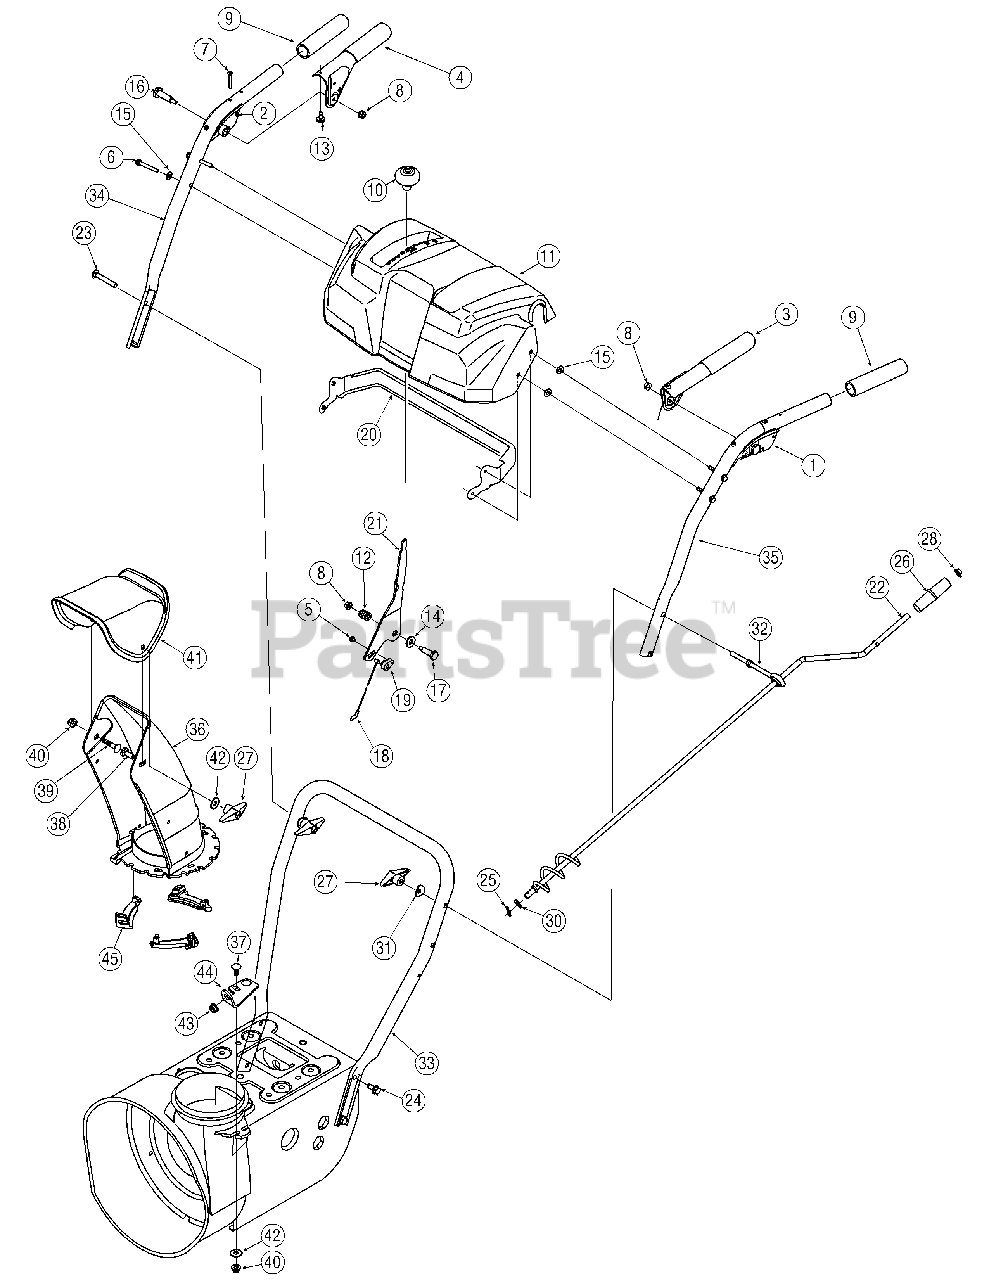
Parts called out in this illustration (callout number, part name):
1	Handle Assembly, Lock, LH
2	Handle Assembly, Lock, RH
3	Handle Ass’ y, Engagement LH
4	Handle Ass’y, Engagement, RH
5	Screw, #10-16, 0.500
6	Screw, 1/4-20, 1.750
7	Screw, Machine, #10-24, 1.375
8	Nut, Flange Lock, 1/4-20, Nylon
9	Grip, 1.0 ID x 5.0
10	Knob, Shift
11	Handle Panel, N-Style
12	Spring, .39 x .60 x .88
13	Bumper, Rubber, .62 OD x .22
14	Washer, Flat, .385 x .870 x .092
15	Washer, Flat, .25 x .630 x.0515
16	Screw, Shoulder, .43 x 1.34, 1/4-20
17	Screw, Shoulder, .374 Dia. X1.05
18	Cable, Speed Selector
19	Barrel Houlder, Cable, LH
23	Screw, Carriage, 5/16-18, 2.25
24	Screw, 5/16-18, 0.75, Gr5
25	Pin, Cotter, .072 x 1.13
26	Crank Knob, 1.0 Dia. x 3.
27	Knob Assembly, Wing Nut, 5/16-18
28	Cap, Push, 3/8 Rod
29	Grommet, .44 ID x .94 OD
30	Washer, Flat, .375 x .738
31	Washer, Saddle, 320 x .93
32	Eye Bolt, Chute Crank
36	Chute, Lower, 5.0 Diameter
37	Bolt, Carriage, 5/16-18, 1.0
38	Nut, Flange Lock, 5/16-18, Nylon
39	Bolt, Carriage, 5/16-18, 1.0
40	Bolt, Carriage, 5/16-18, .750
41	Chute, Upper, w/ Label
42	Washer.349 ID x .879 OD x.063
43	Bushing, Plastic, .380
45	Flange Keeper, Chute
